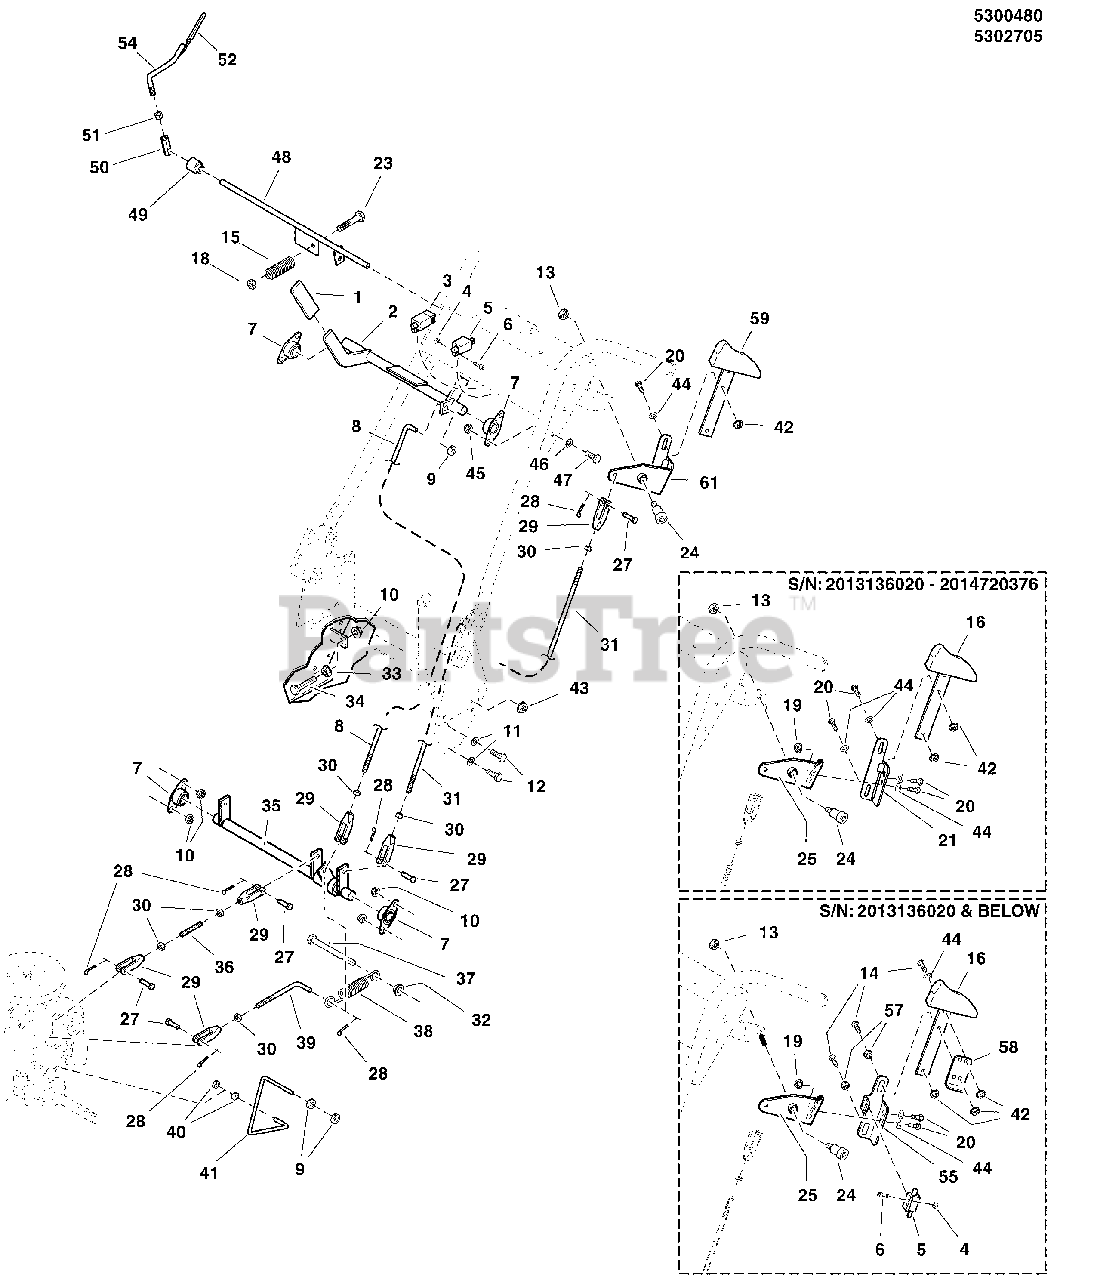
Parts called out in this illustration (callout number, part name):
1	GRIP, FOAM, 1/4" X 1
2	WELD, BRAKE CONTROL
3	SWITCH, PLUNGER, N.O./N.C.
4	NUT, #10-24 HEX
5	SWITCH, Plunger, NC
6	SCREW, #10-24 X 1/2" ROUND PHILLIPS
7	BEARING, BRONZE FLANGE, 3/4
8	ROD, PARKING BRAKE LINKAGE
9	COLLAR, 5/16" SET
10	NUT, 5/16-18 HEX NYLOCK FLANGE
11	WASHER, 5/16" SAE
12	BOLT, 5/16-18 X 3/4" GD5
13	NUT, 3/8-16 HEX SIDE LOCK
13	NUT, 3/8-16 HEX TOP LOCK
14	BOLT, 1/4-20 X 1", GD
15	SPRING, COMPRESSION
16	HANDLE, RUBBER HYDROCUT - LH
18	NUT, 1/4-20 HEX NYLOCK FLANGE (5025391)
19	NUT, 1/4-20 HEX SERR. FLANGE
20	BOLT, 1/4-20 X 3/4" GD5 YZ
21	MOUNT, MOTION CONTROLS, LH
23	BOLT, 1/4-20 X 3, GD5
24	BOLT, 3/8-16 X 1.0", 1/2" SHOULDER
25	WELD, ARM CONTROL, LH
27	PIN, CLEVIS, 5/16" X 1
28	PIN, COTTER, 3/32" X 3/4
29	CLEVIS, 5/16-24, STEEL, CLEAR ZINC
30	NUT, 5/16-24 HEX
31	ROD, THUMB CONTROL LINKAGE
32	NUT, 3/8-16 HEX SERRATED FLANGE
33	NUT, 5/16-18 HEX SERRATED FLANGE (LARGE)
34	BOLT, 5/16-18 X 1 1/2" FLANGE
35	WELD, CONTROL SHAFT
37	BOLT, 3/8-16 X 4" GD5 YZ
38	SPRING, EXT, 3.875 X .70 LOOP
39	LINK, PARKING BRAKE LOWER
40	COLLAR, 1/4" SET
41	LEVER, DUMP VALVE
42	NUT, 1/4-20 HEX NYLOCK FLANGE (5025391)
43	NUT, 3/8-16 HEX NYLOCK FLANGE
44	WASHER, 1/4 SAE (5025154)
45	NUT, 3/8"-16 HEX NYLOCK FLANGE
46	WASHER, 3/8" SAE
47	BOLT, 3/8-16 X 3/4" GD5
48	ROD, OPC SWITCH, PACER
49	SPACER, SHOULDER
50	ADJUSTER, LINKAGE
51	NUT, 3/8-16 HEX
52	GRIP, VINYL, 1/2 X 4
53	WELD, OPERATOR PRESENCE, LH - RED
54	WELD, OPERATOR PRESENCE, RH - RED
55	MOUNT, MOTION CONTROLS, LH
57	SPACER, SLIDE
58	ACTUATOR, SWITCH
59	HANDLE, RUBBER, HYDROCUT - LH
61	WELD, ARM CONTROL - LH - ORG
